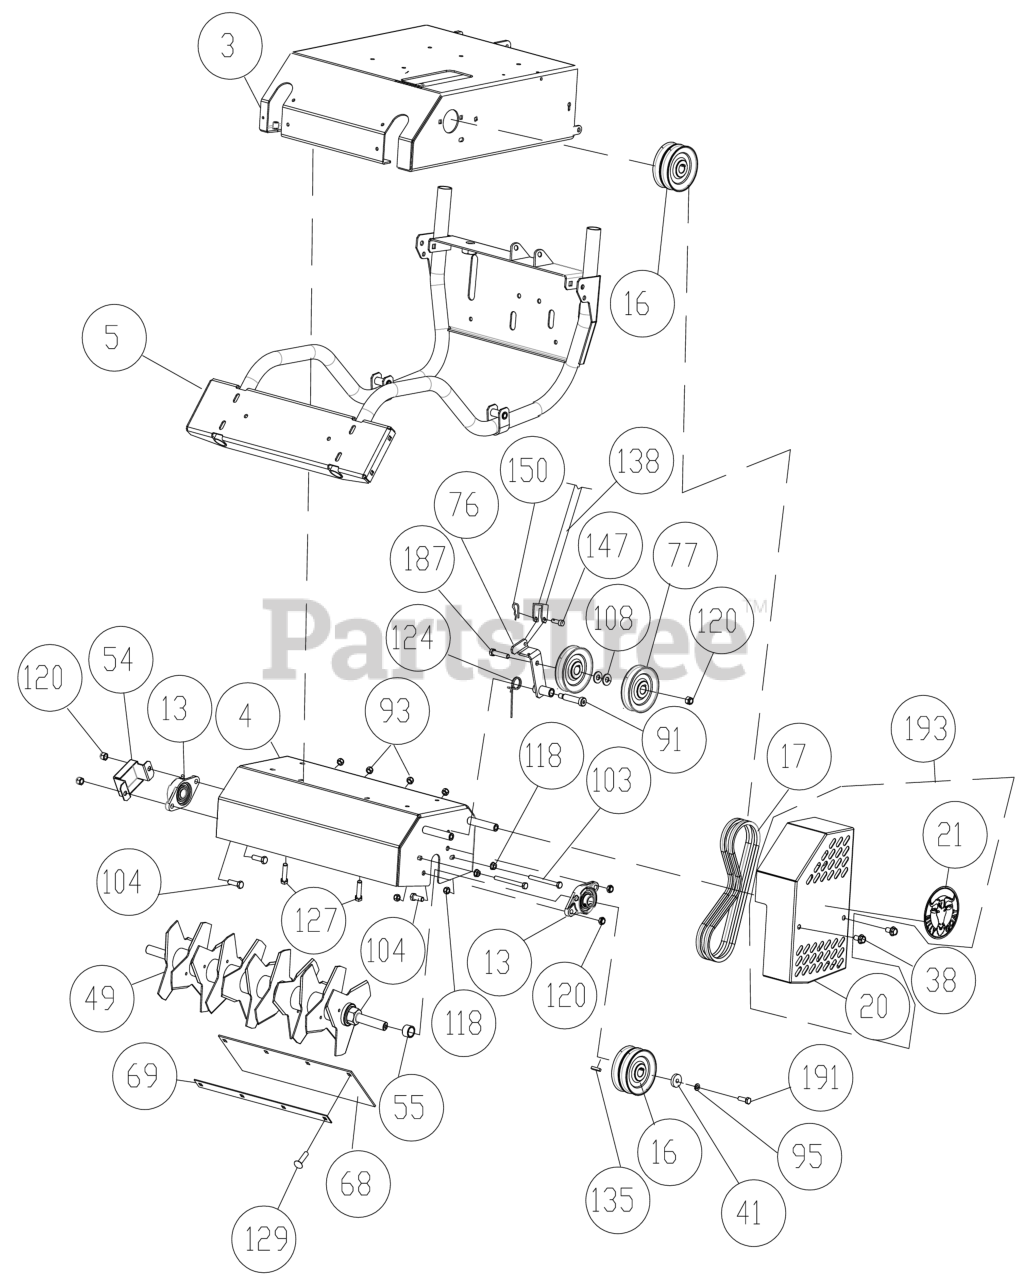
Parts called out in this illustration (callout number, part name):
3	ENGINE BASE WA
4	HOUSING VERTICUTTER WA
5	FRAME SUPPORT OS900SP WA
13	BEARING 3/4" CAST FLANGE W/ZERK
16	PULLEY 0.75" ID X 4" 4L SECTION
17	BELT 6381 POWER RATED
20	GUARD REEL BELT
21	LABEL DECAL SM CIRCLE
38	SER HEX WASHER 3/8" - 16
41	WASHER 1.125 OD X 0.344 ID X .25 THK ZP
49	OSSP REEL KIT (SEE ACCESSORY PRICELIST)
54	GUARD BEARING REEL
55	SPACER SEED BOX AXLE
68	DEFLECTOR RUBBER OS900SP
69	BAR CLAMP DEFLECTOR
76	ARM IDLER WA REEL ENGAGE
77	PULLEY IDLER 2.75" OD X 3/8" BORE
91	BOLT SHOULDER 1/2" X 2"
93	NUT LOCK 5/16"-18 HEX Z/P
95	WASHER LOCK 5/16 ST MED
103	SCREWCAP 5/16"-18X3 1/2" HCS ZP
104	SCREWCAP 3/8"-16 X 1" HCS ZP
108	WASHER 5/16" FLATWASHER Z/P
118	NUT FLANGE 5/16"-18 ZP
120	NUT LOCK 3/8-16 LT WT THIN ZP
124	SPRING IDLER MULE DRIVE
127	SER HEX WASHER FLNG SCREW 5/16"-18 X 3/4"
129	BOLT CARRIAGE 5/16"-18 X 3/4" ZP
135	KEY 3/16" SQ X 1 1/4"
138	CABLE CLUTCH SEEDING CONTROL
147	PIN CLEVIS 1/4" X .75"
150	PIN CLIP HITCH 0.051 X 3/4"
187	SCREWCAP 3/8"-16X2 1/2" HCS ZP
191	SCREWCAP 5/16"-24 X 1" GR.8 ZP W/PATCH
193	GUARD REEL BELT W/LABELS
